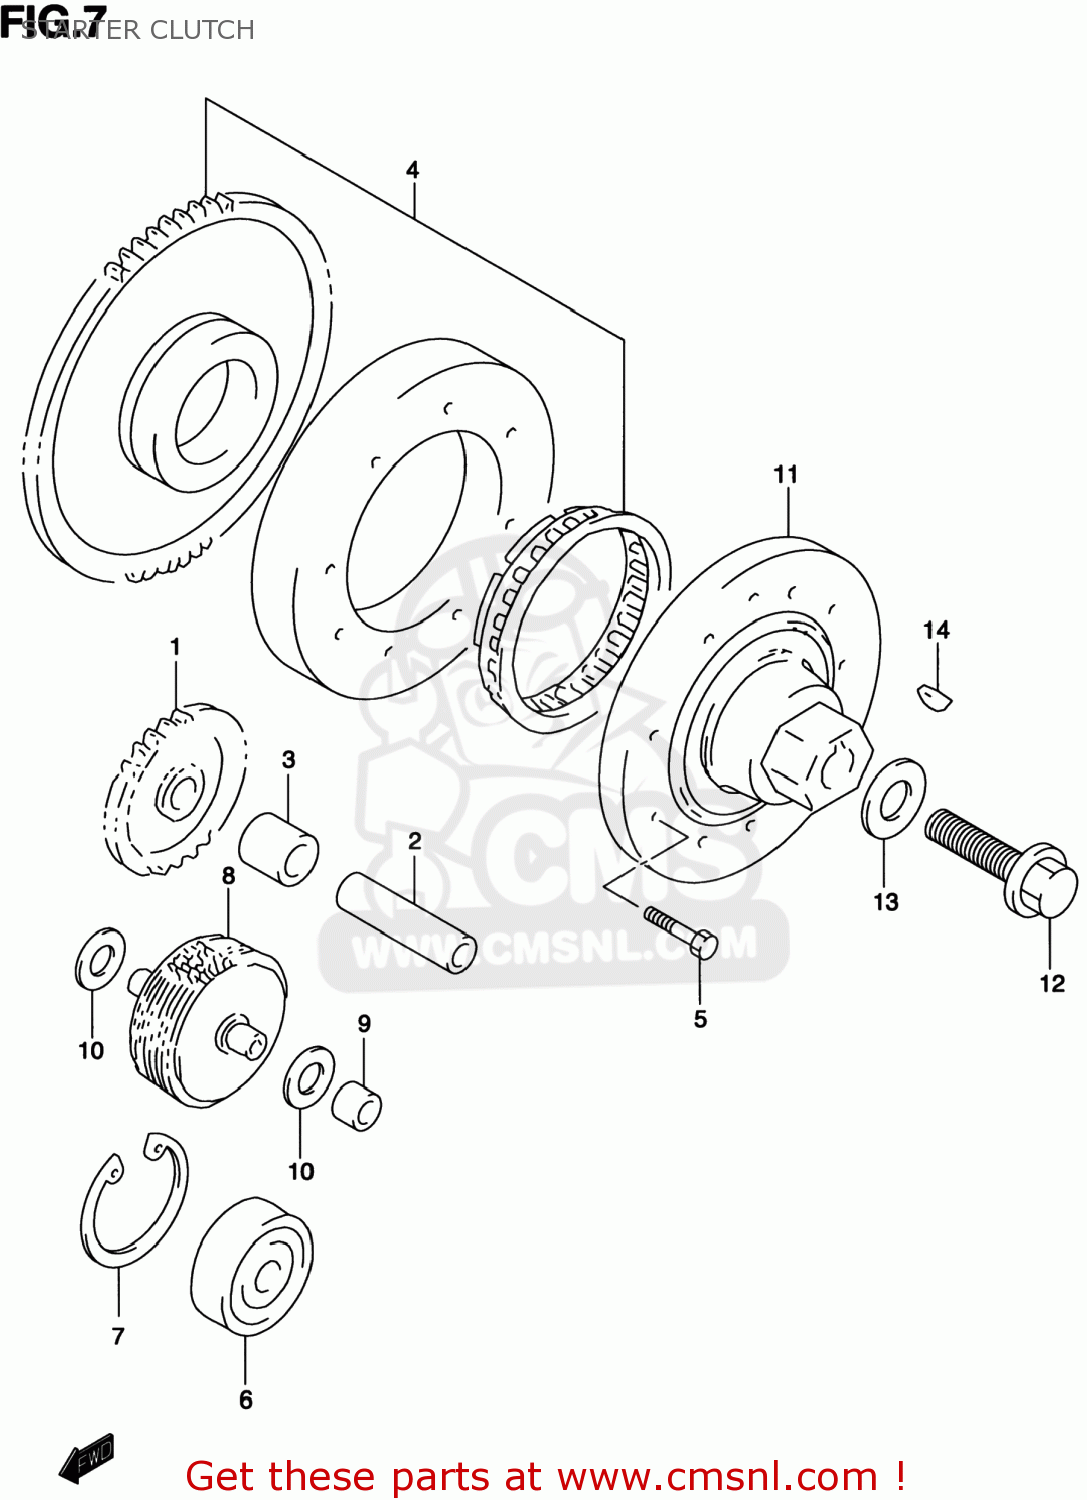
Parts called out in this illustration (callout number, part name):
1	GEAR,STARTER IDLE NO.2
2	PIN(7X12X50.5)
3	SPACER(12.5X19X17.5)
4	CLUTCH SET,STARTER
5	BOLT
6	BEARING(12X28X8)
7	CIRCLIP
8	LIMITER ASSEMBLY,STARTER IDLER GEAR
9	BUSH,LIMITER GEAR SHAFT
10	WASHER
11	HOUSING,STARTER CLUTCH
12	BOLT(12X40)
13	WASHER(12X30X3)
14	KEY
